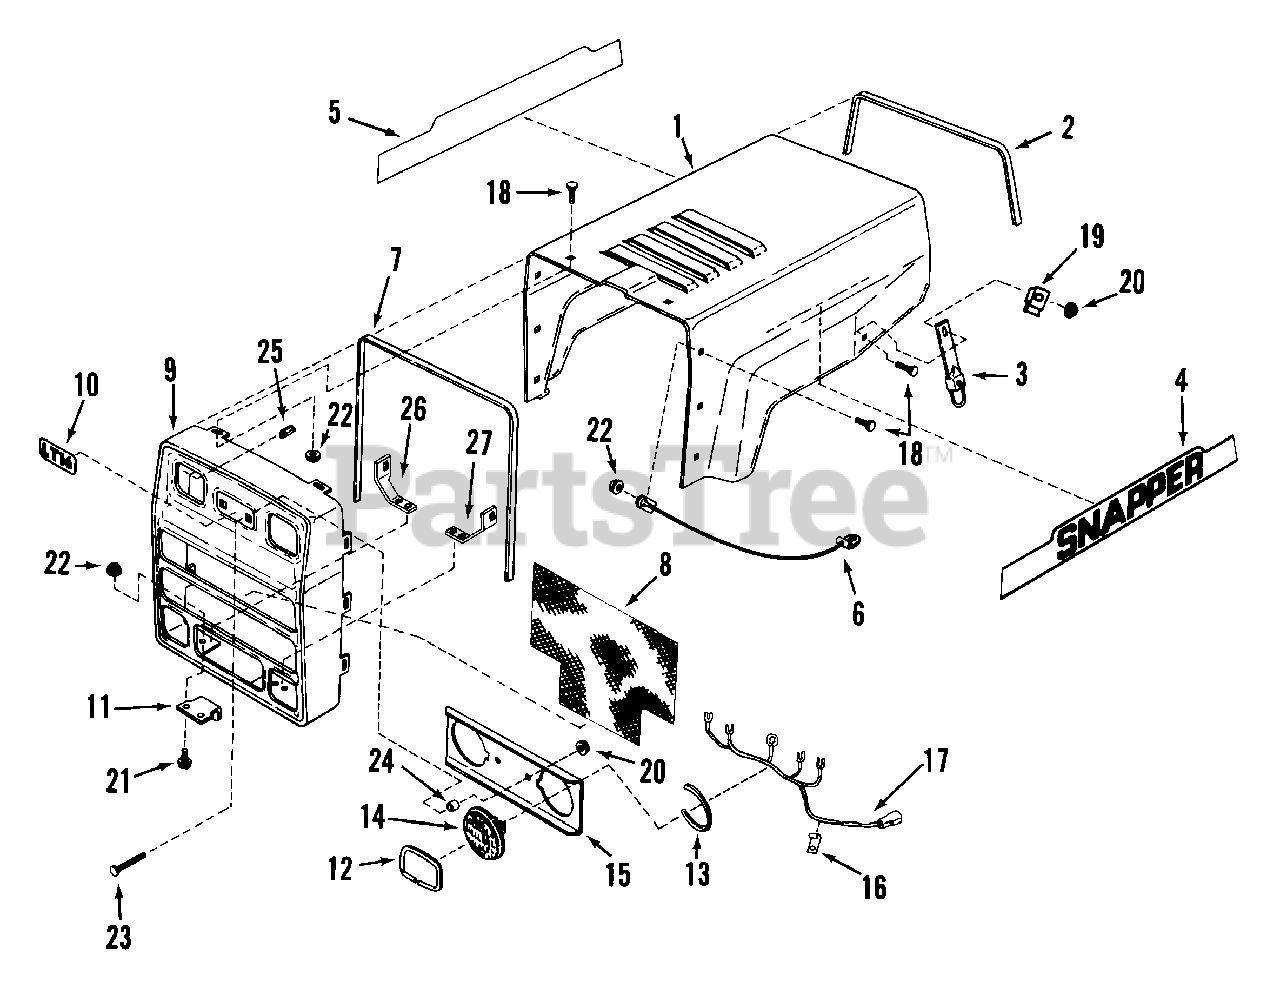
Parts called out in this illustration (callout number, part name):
1	HOOD, LT16 Series Tractor
2	TRIM, Rear Edge Hood
3	LATCH, Hood Retaining
4	DECAL, SNAPPER (Left Side)
5	DECAL, SNAPPER (Right Side)
6	CABLE, Hood Stop
7	GASKET, Grille
8	MESH, Grille
9	GRILLE
10	DECAL, LT16
11	HINGE, Hood
12	GASKET, Head Lamp
13	GASKET, Head Lamp to Bracket
14	HEAD LAMP
15	BRACKET, Head Lamp
16	CLIP, Wiring Harness
17	HARNESS, Head Lamp Wiring
18	BOLT, 1/4-20 x 5/8" Flat Head Carriage
19	CLIP, Hood Retainer
20	NUT, 1/4-20 Hex Flange Lock, Grade 5
21	BOLT, 1/4-20 x 5/8" Hex Flange Lock, Grade 5
22	NUT, 1/4-20 Hex Flange Lock, Grade 5
23	BOLT, 1/4-20 x 1-1/4" Flat Head Carriage
25	CLIP
26	BRACE, Grille- R.H.
27	BRACE, Grille- L.H.
